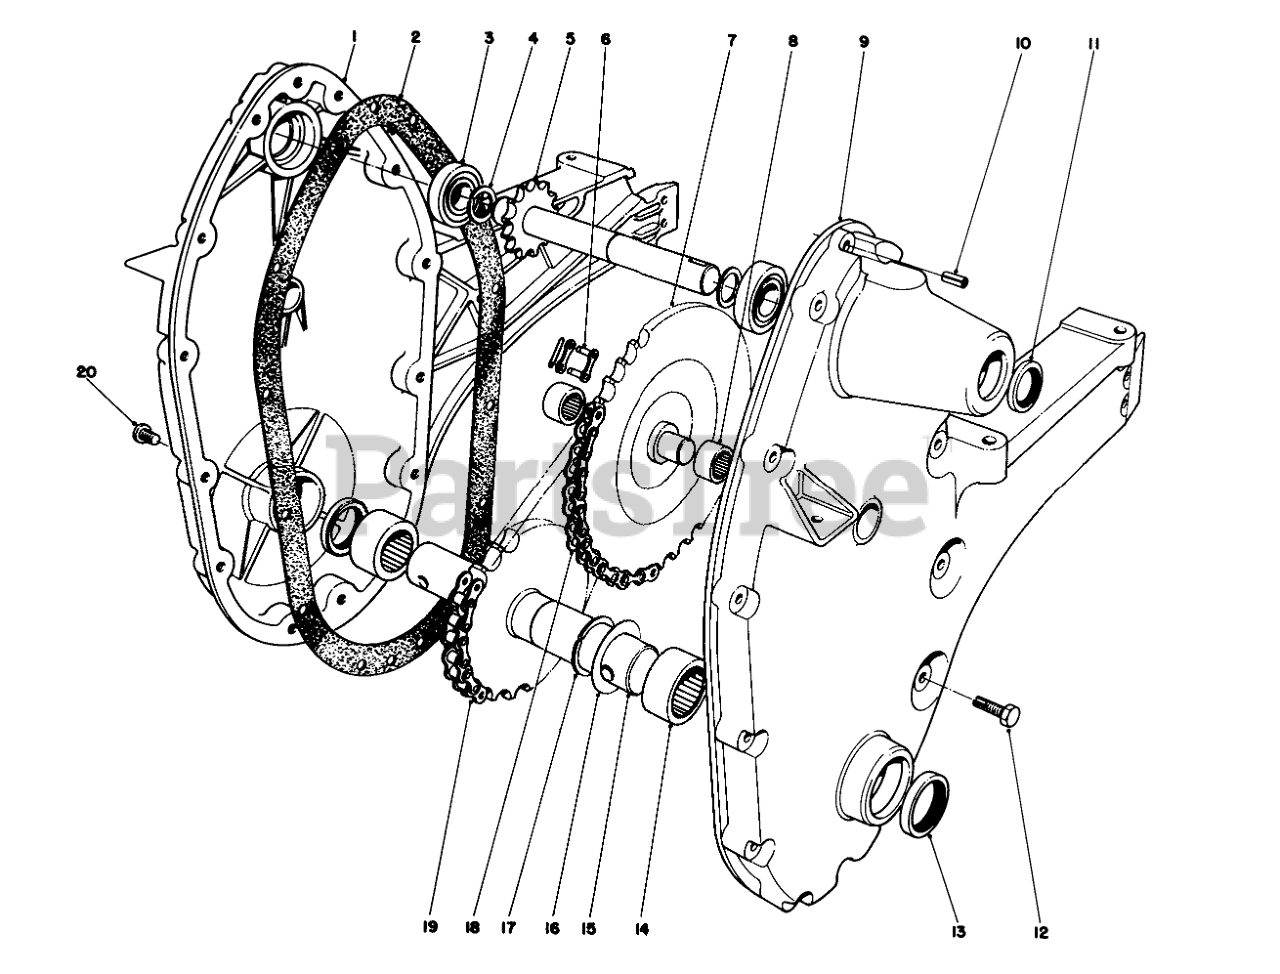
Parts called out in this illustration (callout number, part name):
1	Chain Case R H.
2	GASKET TILLER
3	BALL BRG
4	5/8X030 EX MED RING
5	Upper Shaft
6	LINK-CONNECTING, NO. 35
7	Sprocket Cluster
8	NEEDLE BRG
9	Chain Case L.H.
10	PIN-ROLL
11	SEAL-OIL
12	SCREW-HH
13	SEAL-OIL
14	NEEDLE BRG
15	Tine Shaft
16	Washer
17	Snap Ring
18	Roller Chain
19	Roller Chain
